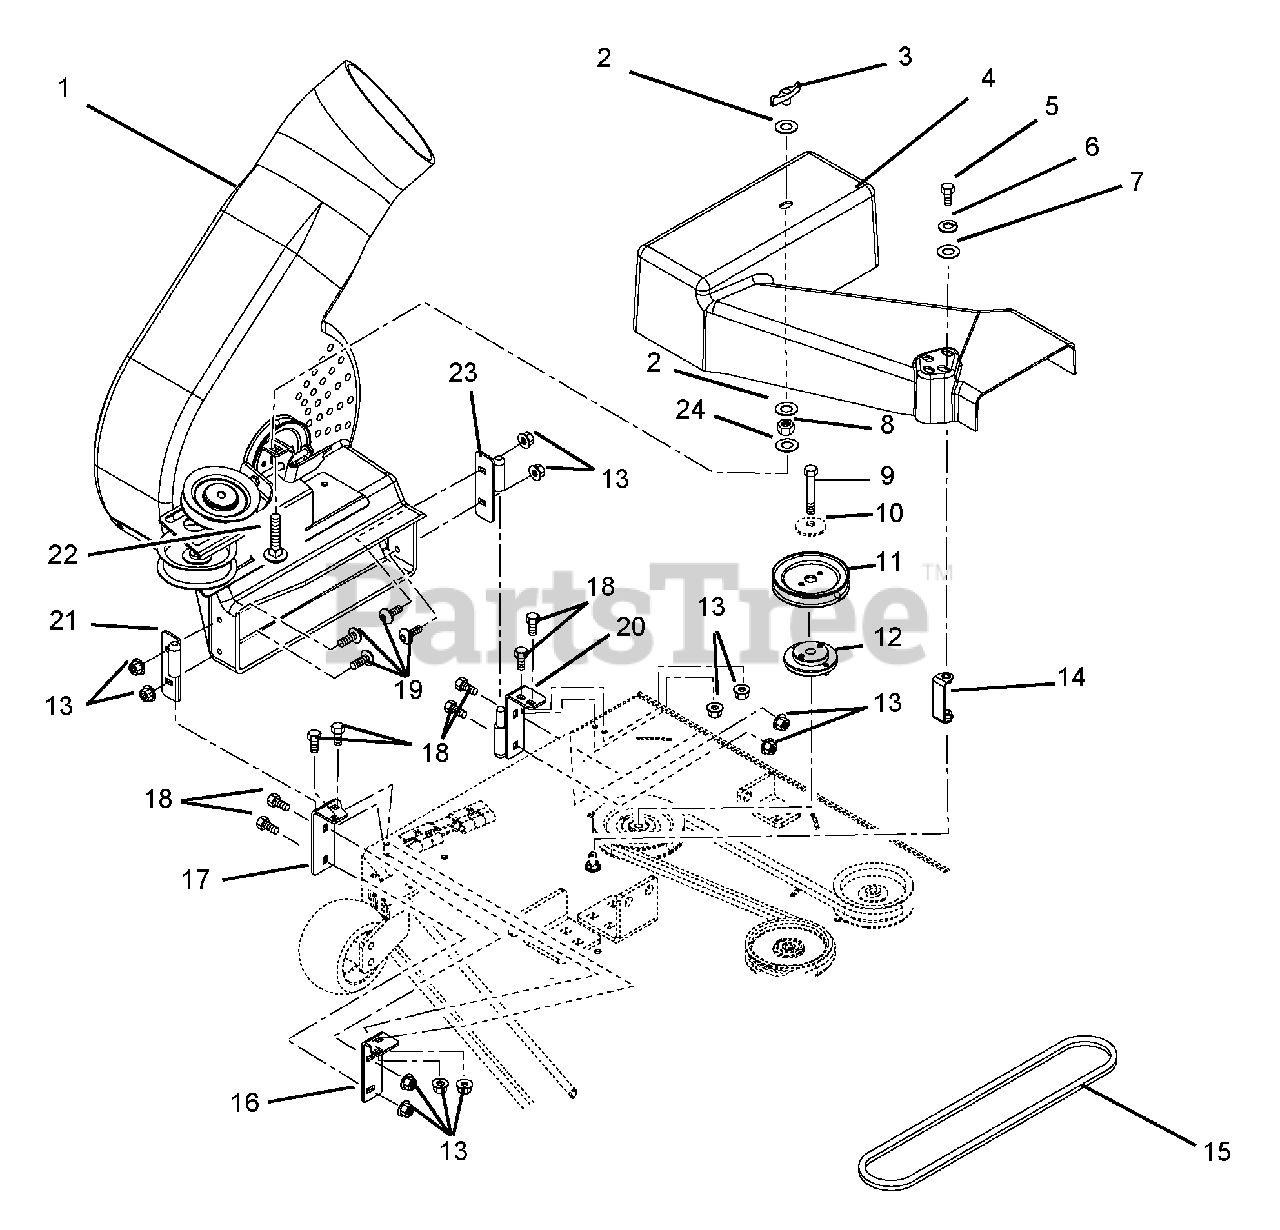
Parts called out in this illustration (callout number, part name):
1	Housing, Blower
2	Washer-Flat-Steel .38 x 1.50 x .062
3	Knob- Wing .312-18
4	Belt Cover
5	Bolt-Hex .38-16 x .75 - Grade 5
6	Washer-Locking .38 x .094 Regular
7	Washer-Flat-Steel .438 x 1.00 x .083
8	Nut-Jam .312-18
9	Bolt-Hex .38-16 x 1.75 - Grade 8
10	Washer, Cupped, .375 (comes with mower deck)
11	Sheave, 3.00 Diameter (44-inch Mower Decks)
11	Sheave, 4.00 Diameter (48-inch Mower Decks)
12	Assembly, Sheave Adapter
13	Nut-Locking-Top-Flange .25-20
14	Spacer, Cover
15	V-Belt (44-Inch Mower Decks)
15	V-Belt (48-Inch Mower Decks)
16	Bracket, Front
17	Weldment, Front Mount Bracket
18	Bolt-Hex .25-20 x .75 - Grade 5
19	Screw-Machine .25-20 x .75
20	Weldment, Rear Mount Bracket
21	Weldment, Housing Mount Right Hand
22	Bolt-Round Head Square Neck .31-18 x 1.50
23	Weldment, Housing Mount Left Hand
24	Washer, Flat Steel .312 x .734 x .065
